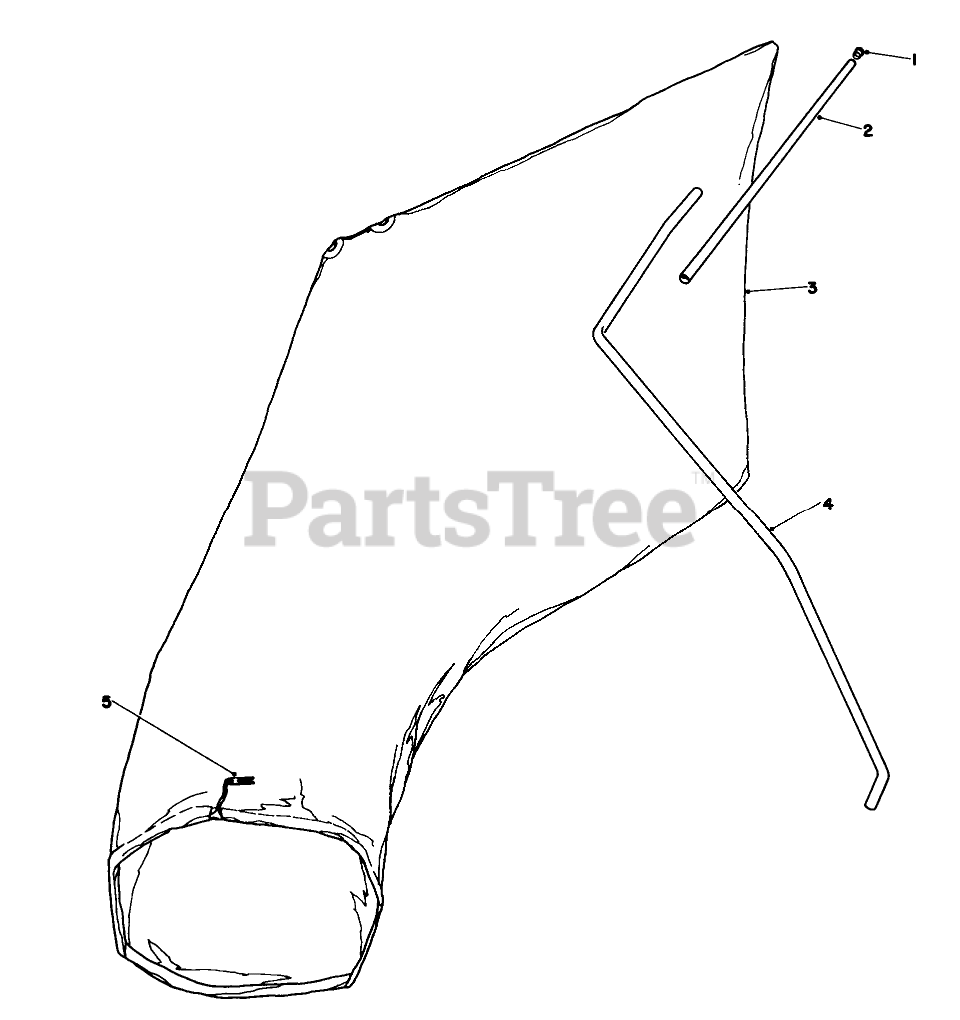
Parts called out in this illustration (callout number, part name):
2	BAG HANGER TUBE
3	GIANT BAG(29-9860) WW
4	HANGER ROD
5	BAG CORD FASTENER
